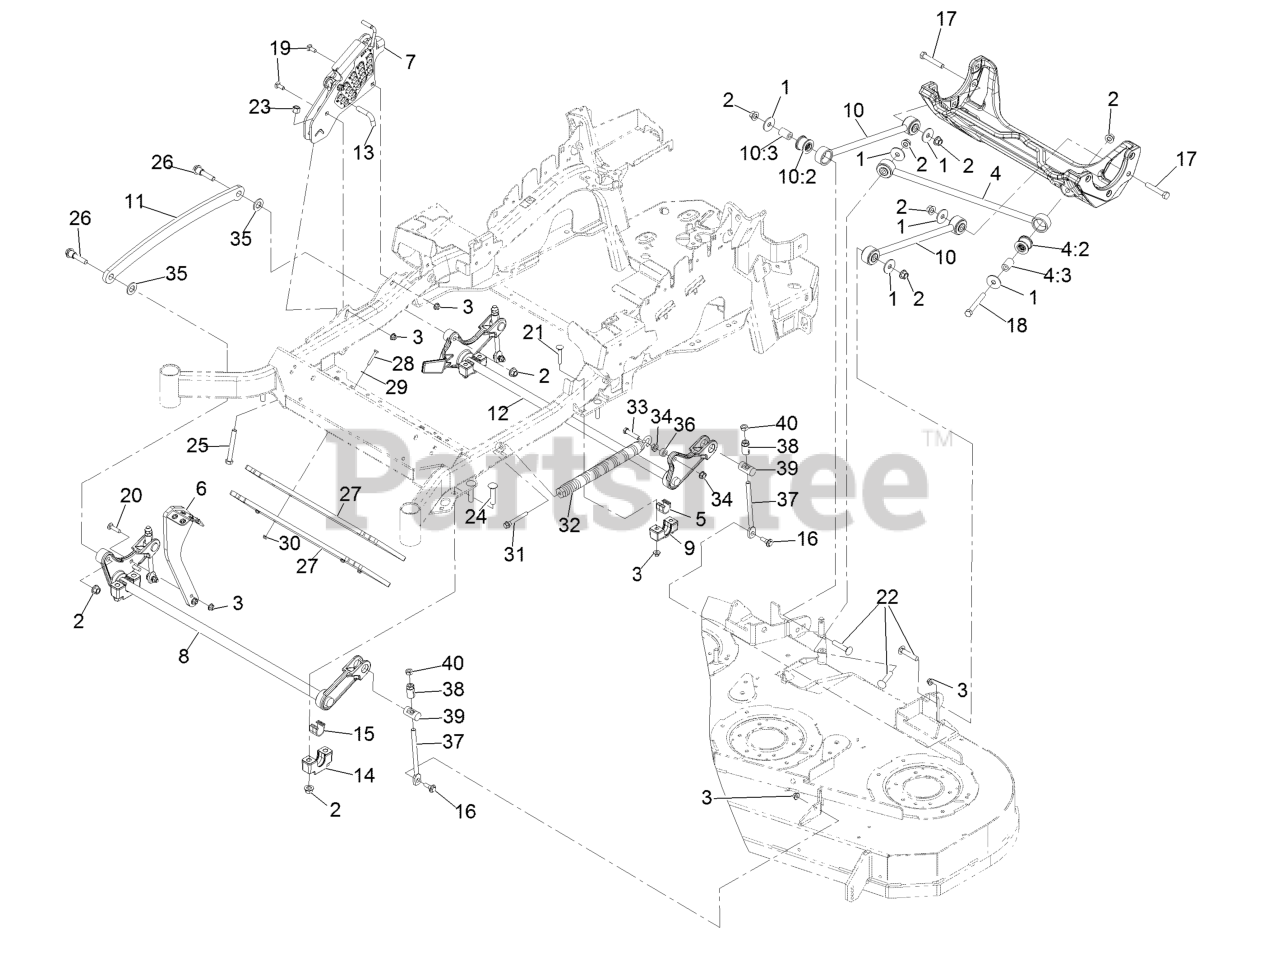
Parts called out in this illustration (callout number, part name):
2	Nut-Lock 1/2-13
3	Nut-Nyloc 3/8-16 Flg
4	Panhard Rod ASM
4:2	Bushing-Suspension,Rubber
5	Bearing-Cross Shaft, Rear
6	Lever-Foot
7	HOC ASM
8	Decklift-Front
9	Support-Cross Shaft,Bearing Rear
10	Deck Strut ASM
10:2	Bushing-Suspension,Rubber
11	Link-Lift, Deck
12	Lift-Deck, Rear
13	Pin-HOC
14	Support-Cross Shaft,Bearing Bearing
15	Bearing-Cross Shaft, Front
16	Screw-Hex Flange 3/8-16 X .80
17	Screw-HH 1/2-13 X 3
18	Screw-HH 1/2-13 X 4
19	Bolt-Carriage 3/8-16 X 1
20	Bolt-Carriage 3/8-16 X 1 1/2
21	Bolt-Carriage 3/8-16 X 2 1/4
22	Bolt-Carriage 1/2-13 X 2 1/2
23	Nut-Nyloc 1/2-13
24	Bolt-Carriage 1/2-13 X 2 1/2 Spl Neck
25	Bolt-HH 1/2-13 X 4 Tap
26	Screw-Hex Flange 1/2-13 X 1.90
27	Weight-Toe Board
28	Screw-HH 1/4-20 X 1 3/4
29	Washer-1/4 SAE
30	Nut-Nyloc 1/4-20 Flg
31	Screw-Shcs 3/8-16 X 2.212
32	Spring-Extension
33	Screw-HH 7/16-14 X 2
34	Nut-Whizlock 7/16-14
35	Washer-3/4 SAE
37	Link-Adjuster, Deck Lift
38	Adjuster-Lift, Deck
39	Trunnion
40	Nut-Jam 1/2-13
